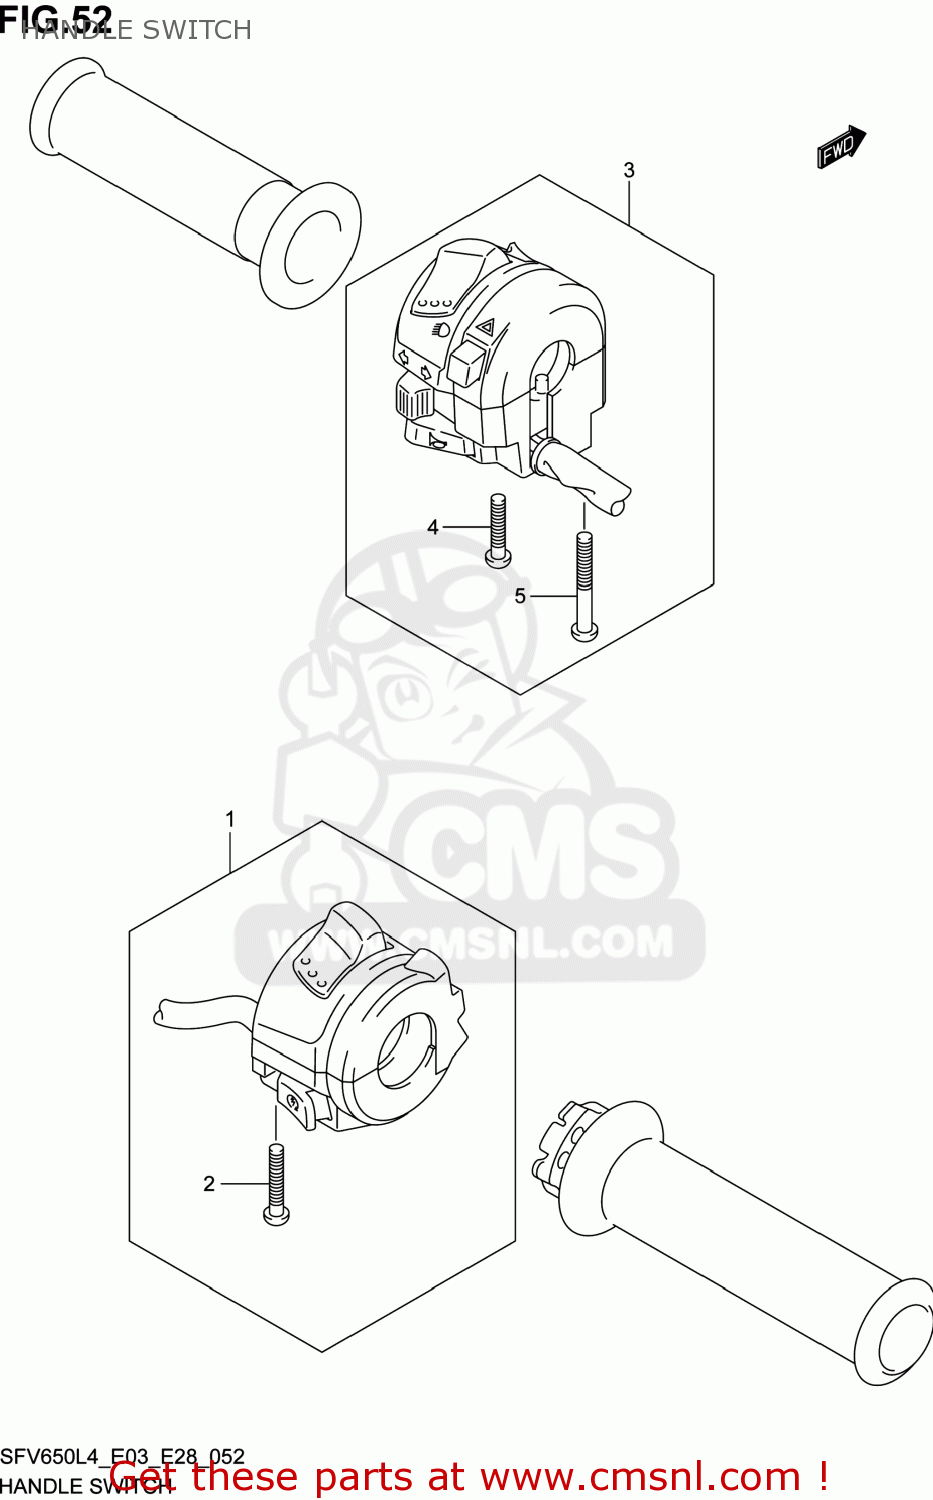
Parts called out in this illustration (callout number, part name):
1	SWITCH ASSY,HANDLE,R
2	SCREW
3	SWITCH ASSY,HANDLE,L
4	SCREW
5	SCREW
